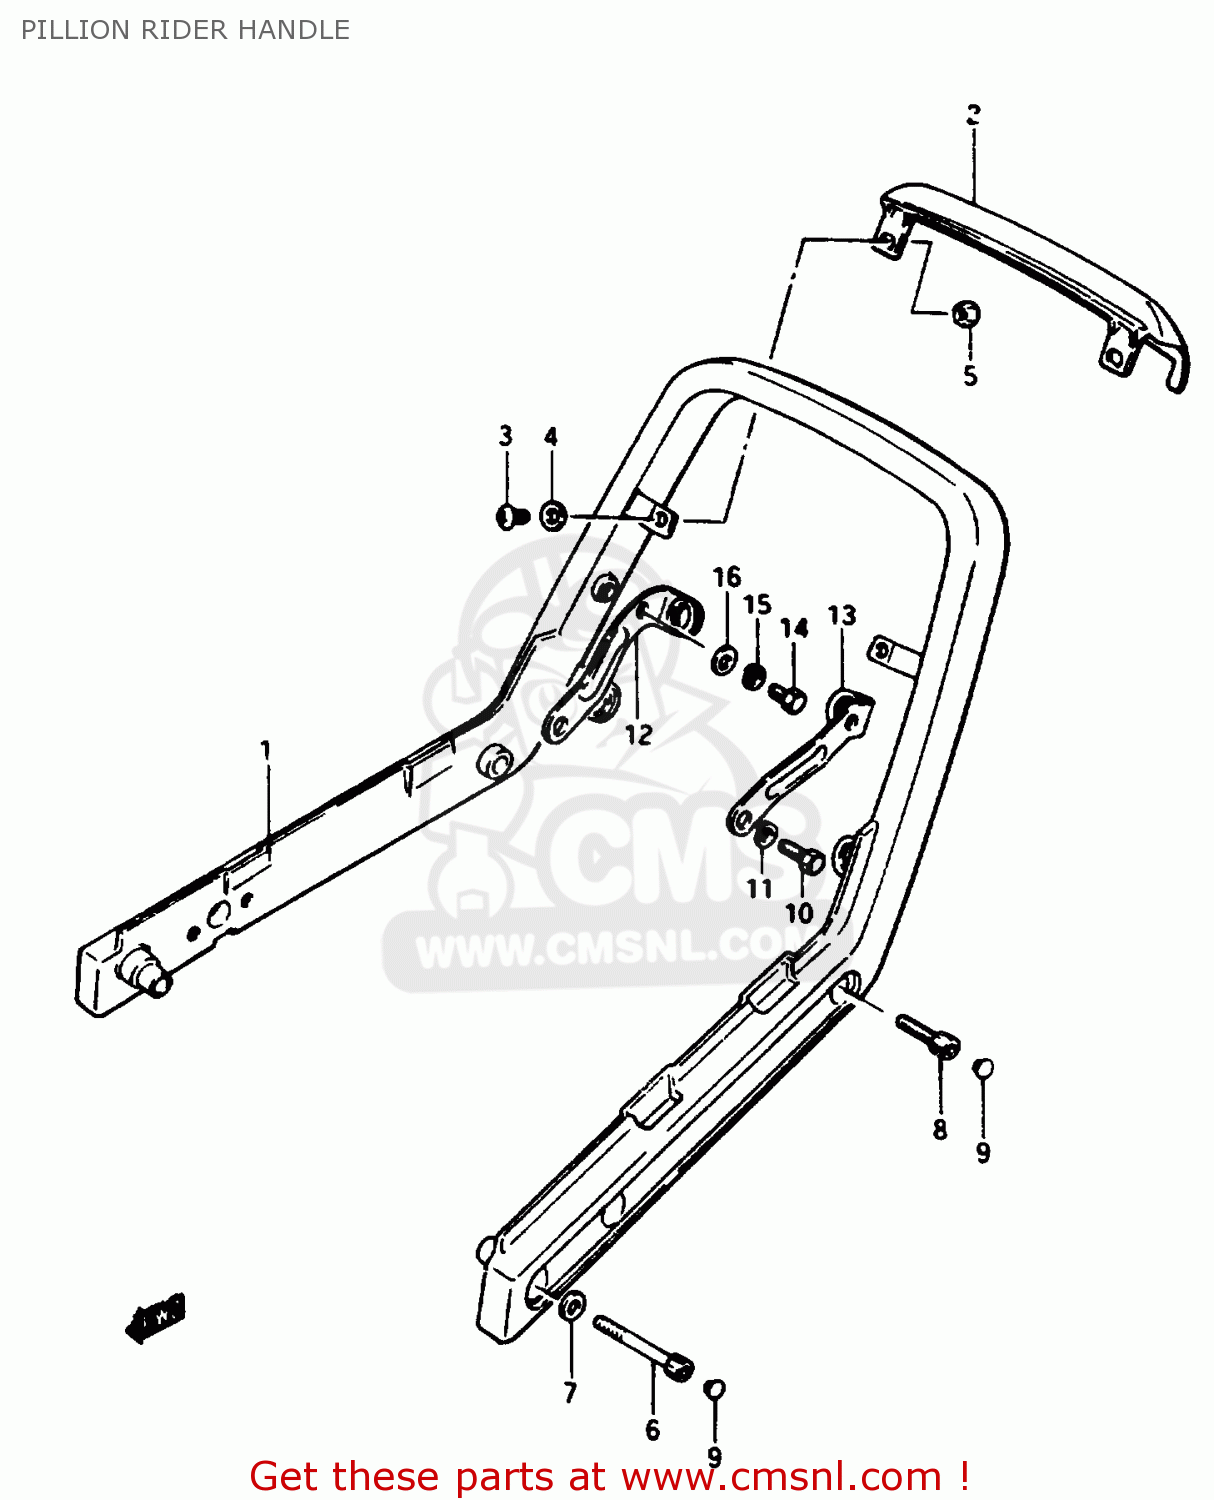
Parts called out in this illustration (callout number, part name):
1	HANDLE,PILLION RIDER
2	COVER,PILLION RIDER HANDLE
3	SCREW
4	WASHER
5	NUT
6	BOLT
7	WASHER
8	BOLT
9	CAP(OD:10)
10	BOLT, 8X1.25X1
11	WASHER,LOCK,8.
12	PLATE,PILLION RIDER HANDLE
13	PLATE,PILLION RIDER HANDLE
14	BOLT 8X12
15	WASHER,LOCK,8.
16	WASHER 8MM
